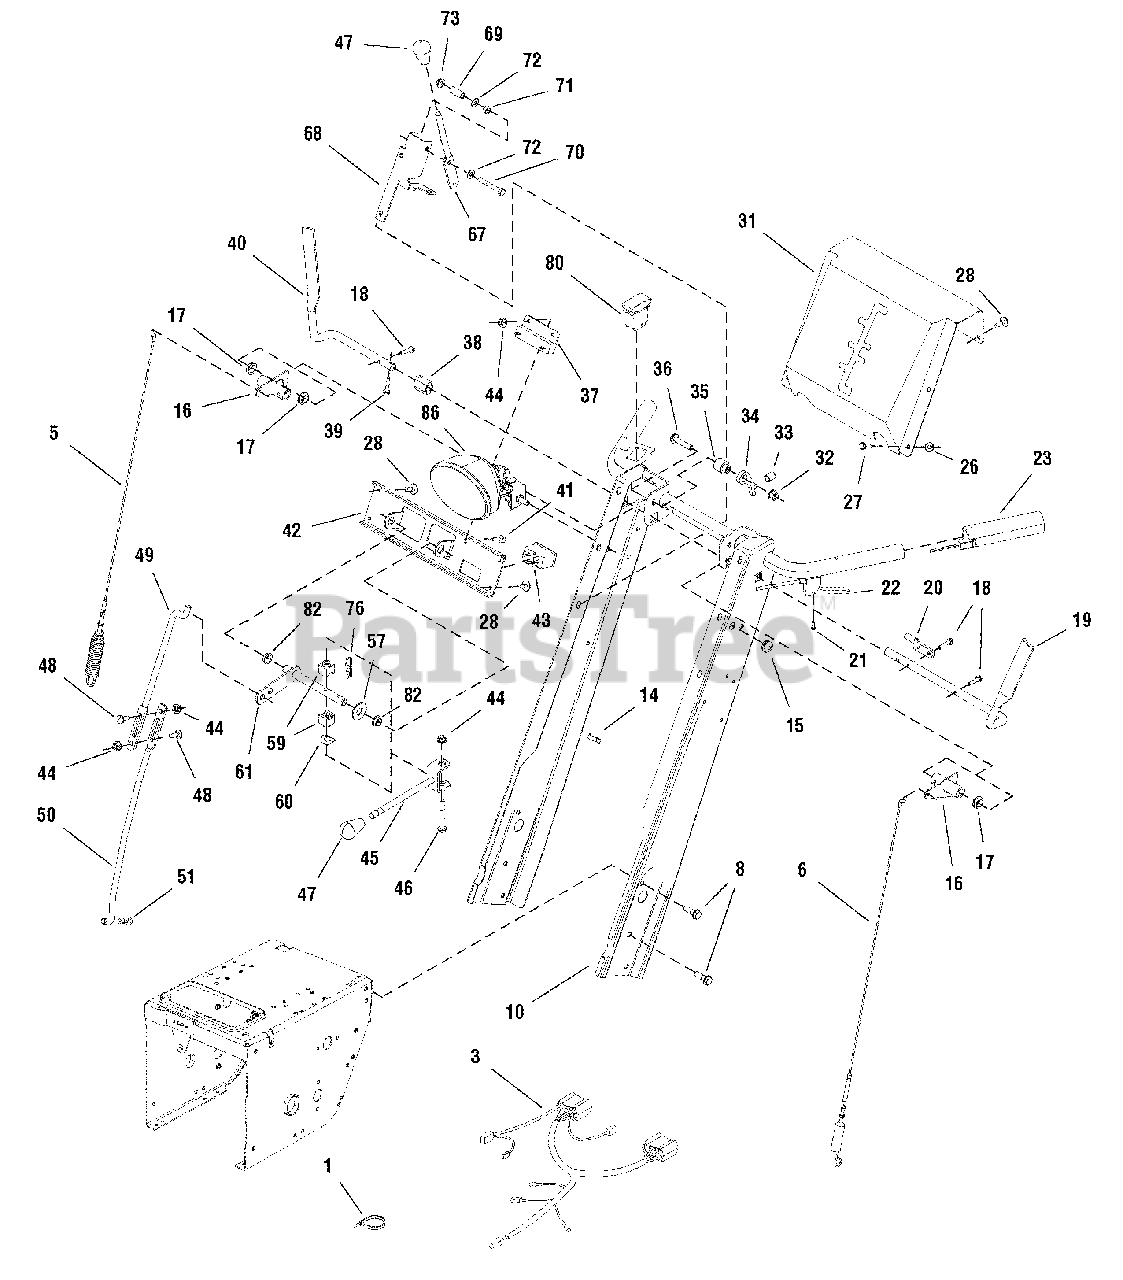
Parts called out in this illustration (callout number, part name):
1	TIE, Self Locking .184 Wide 7.31 Long
3	HARNESS, Hand Warmers/Spout
5	CABLE & SPRING ASSEMBLY, R.H. Auger
6	CABLE & SPRING ASSEMBLY, L.H. Traction
8	SCREW, Hex Head SER Flange Taptite, R5/16-18 x 1
10	HANDLE ASSEMBLY, Channel
14	CLIP, Speed Wire
15	GROMMET, 1/2 Diameter
16	LEVER & TUBE ASSEMBLY, Clutch
17	BUSHING, .52 ID x .585 Square x .22 Long Nylon
18	SCREW, Hex Washer Head Taptite, #12-24 x 1
19	HANDLE, Clutch L.H.
20	ROD, Control, 3/8 Diameter, 2.81 Long 2" Flat
21	SCREW, Pan Head Torx #10 x 1/2 Thick
22	CABLE & HANDLE ASSEMBLY
23	HAND GRIP, Heated
26	NUT, Hex Whiz Lock Flange, 1/4-20
27	CAPSCREW, Hex Washer Head, 1/4-20 x 3/4, G5
28	SCREW, Hex Washer Head Taptite, 1/4-20 x 3/4
32	NUT, Hex Flange 5/16-18 ESNA
33	SPRING, Compression, .38 ID x 1 Long
34	LATCH, Control, Powdered Metal
35	SPACER, .328 ID x .81 OD x .94 Long 1/2
36	SCREW, Hex Whiz Lock Flange, 5/16-18 x 1-1/2
37	RESISTOR BLOCK, 1.53
38	GUIDE, Control, .434 Wide 1.08 Long, Powdered Metal
39	SCREW, Hex Washer Head Taptite #10-24 x 1
40	HANDLE, Clutch R.H.
41	CAPSCREW, Hex Head 1/4-20 x 3/4, G5
42	BRACKET, Shift Control
43	SWITCH, Hand Warmer
44	NUT, Hex Keps, 1/4-20 Conical Washer
45	ROD & CLEVIS ASSEMBLY, Shift
46	SCREW, Hex Whiz Lock Flange, 1/4-20 x 2-1/4
47	KNOB, Hole, .357 Diameter 1.14 Diameter, Sphere Softer
48	CARRIAGE BOLT, 1/4-20 x 3/4, G5
49	ROD, 3/8 Diameter, 11.38 Long
50	ROD, Shift Lower
51	PIN, Quick
57	WASHER, 0500 .53 ID x 1-1/4 x .08 Thick
59	BLOCK, Pivot
60	WASHER, Curved, .525 ID x .98 OD x .014 Thick
61	ROD & ARM ASSEMBLY, Pivot,
67	HANDLE, Deflector Control
68	BRACKET, Deflector Control
69	SPRING, Deflector Control
70	CAPSCREW, Hex Head 1/4-20 x 2
72	WASHER, 1/4
73	NUT, Hex Flange 1/4-20 ESNA
76	CLIP, Hair Pin
80	SWITCH, Chute Rotator
82	BUSHING, 1/2 ID x 3/4 OD x 1/4 Long Nylon
86	HEADLIGHT ASSEMBLY, Oval Amber
